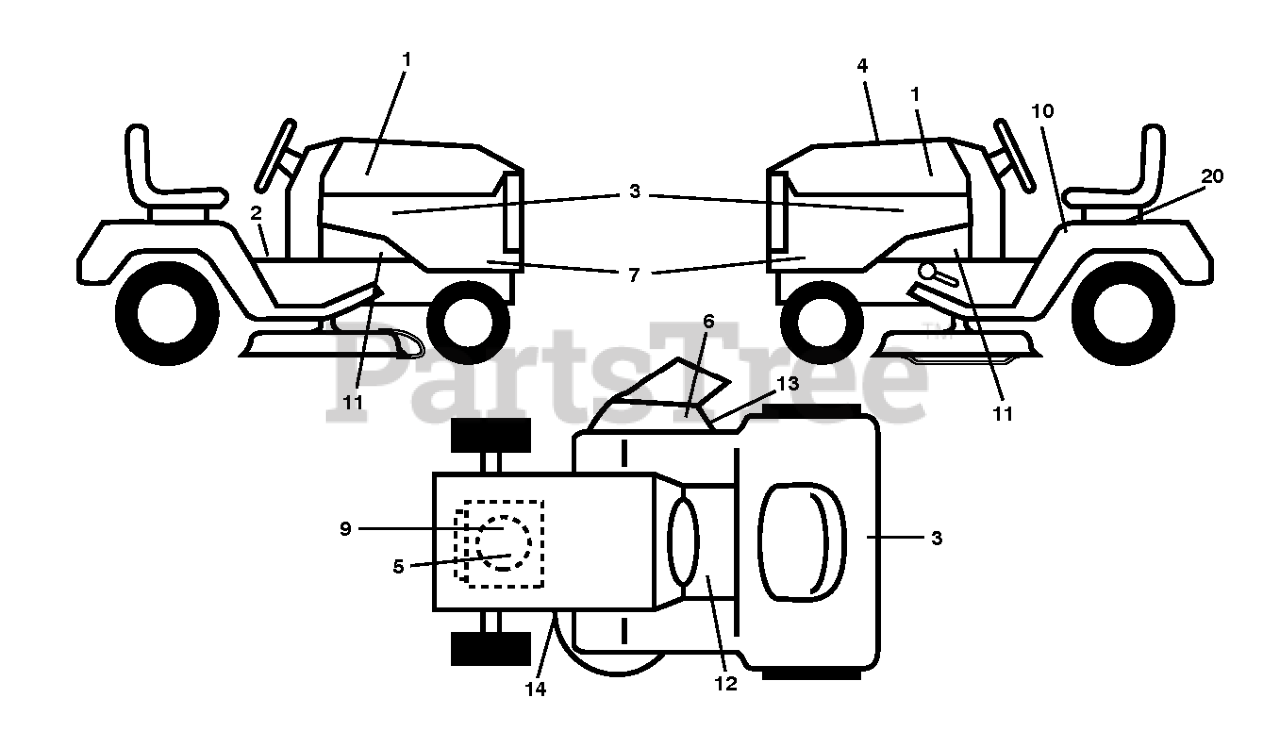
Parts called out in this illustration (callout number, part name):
2	DECAL.PARKING.BRAKE.SADDLE.LT
3	DECAL HOOD
5	DECAL.ENGINE.WARNING
8	DECAL.CUTFINGER.CE.02
9	DECAL.ENG.BS.3125SER.PB.279738
10	DECAL.READ.OWN.MAN.SYMBOL.LT
11	DECAL.CHASSIS.HOT.MUFFLER
12	DECAL.FNDR.SDLE.BRAKE.CLUTCH.6
13	DECAL.DFLCTR.WARNNG.CTFNGR.SYM
14	DECAL.DECK.SCH.36,38,94.NONCR
20	DECAL BTRY SYMBOLS
